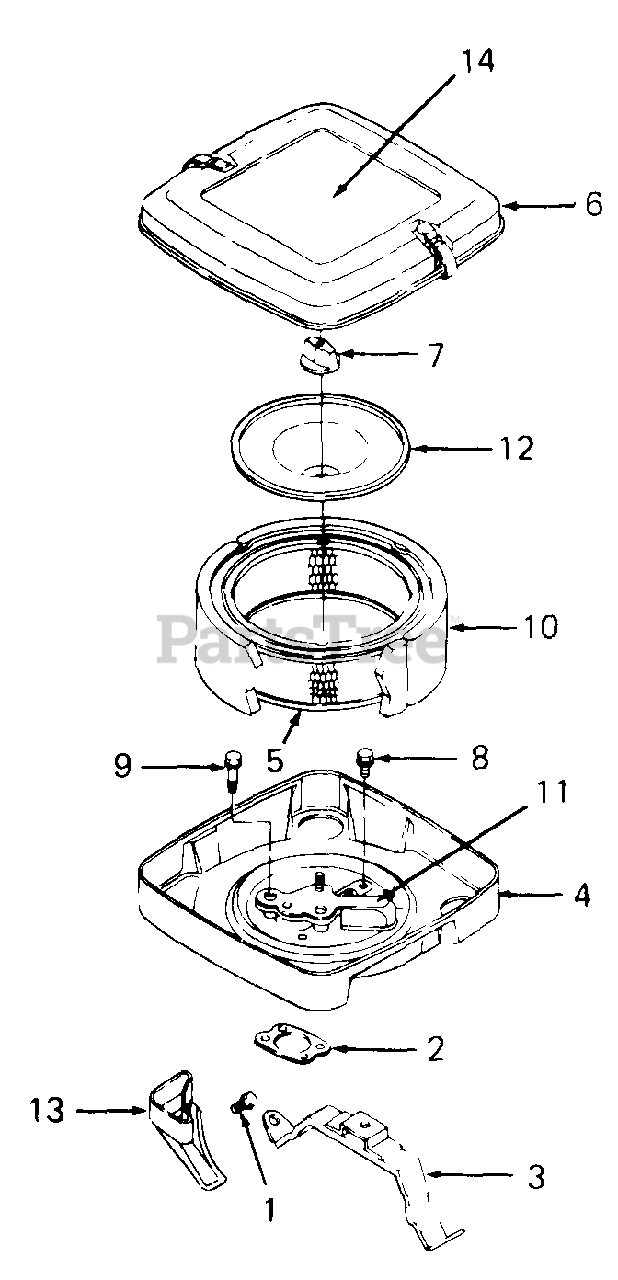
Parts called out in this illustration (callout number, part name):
1	Screw, Sems
2	Gasket, Air Cleaner
3	Bracket, Air Cleaner
4	Base, Air Cleaner
5	Cartridge, Air Cleaner
6	Cover, Air Cleaner
7	Knob, Air Cleaner
8	Screw, Sems
9	Screw, Sems
10	Element, Foam
11	Shield Assy
12	Plate, Air Cleaner
13	Tube, Air Inlet
14	Label, Vanguard Engine
